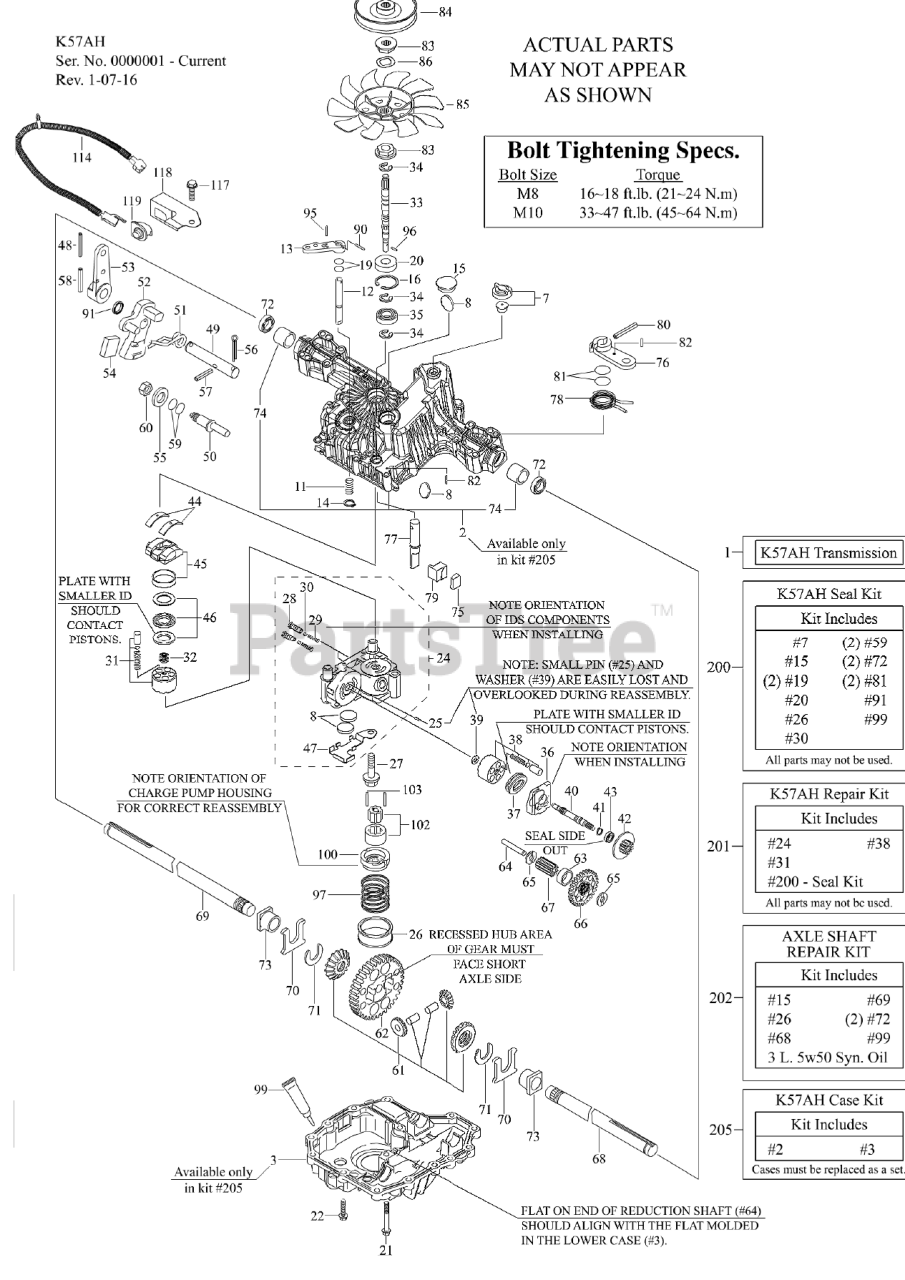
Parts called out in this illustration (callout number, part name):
22	TAPPING SCREW
41	SNAP RING S15
72	RP SEAL.19, 19216334280
78	RETURN SPRING
84	PULLEY.INPUT.FLANGED.TRANSAXLE
85	FAN.BLACK.1A646083070
114	HARNESS ASSY
